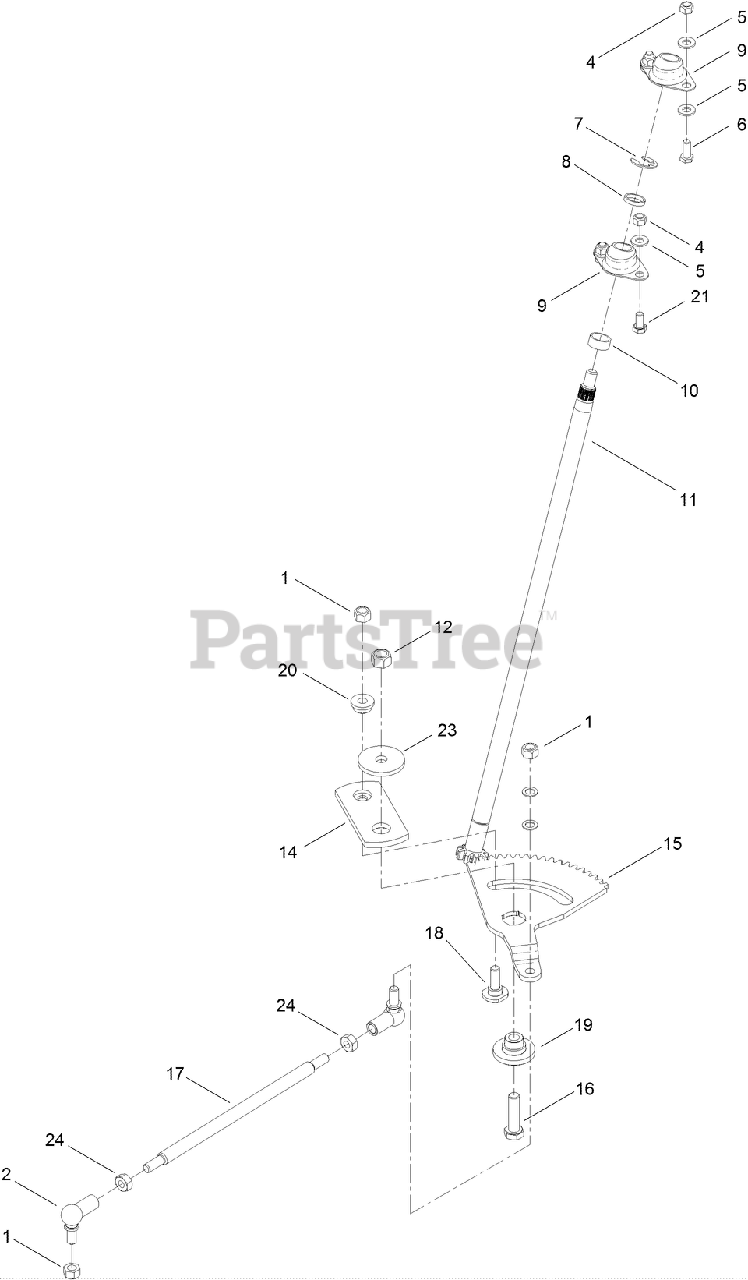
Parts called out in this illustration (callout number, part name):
1	NUT-LOCK, NI
2	JOINT-BALL, ANGLE
4	NUT-LOCK, NI
5	WASHER-PLAIN
6	SCREW-HH
7	CLIP-SPRING
8	SPACER-UPPER
9	BEARING-SPHERICAL
10	SPACER-LOWER
11	Shaft-Steering
12	NUT-HEX
14	Plate-Steering
15	GEAR-SECTOR
16	SCREW-HH
17	LINK-DRAG
18	Bolt-Shoulder
19	Pivot-Steering
20	Bushing
21	SCREW-HH
23	WASHER
